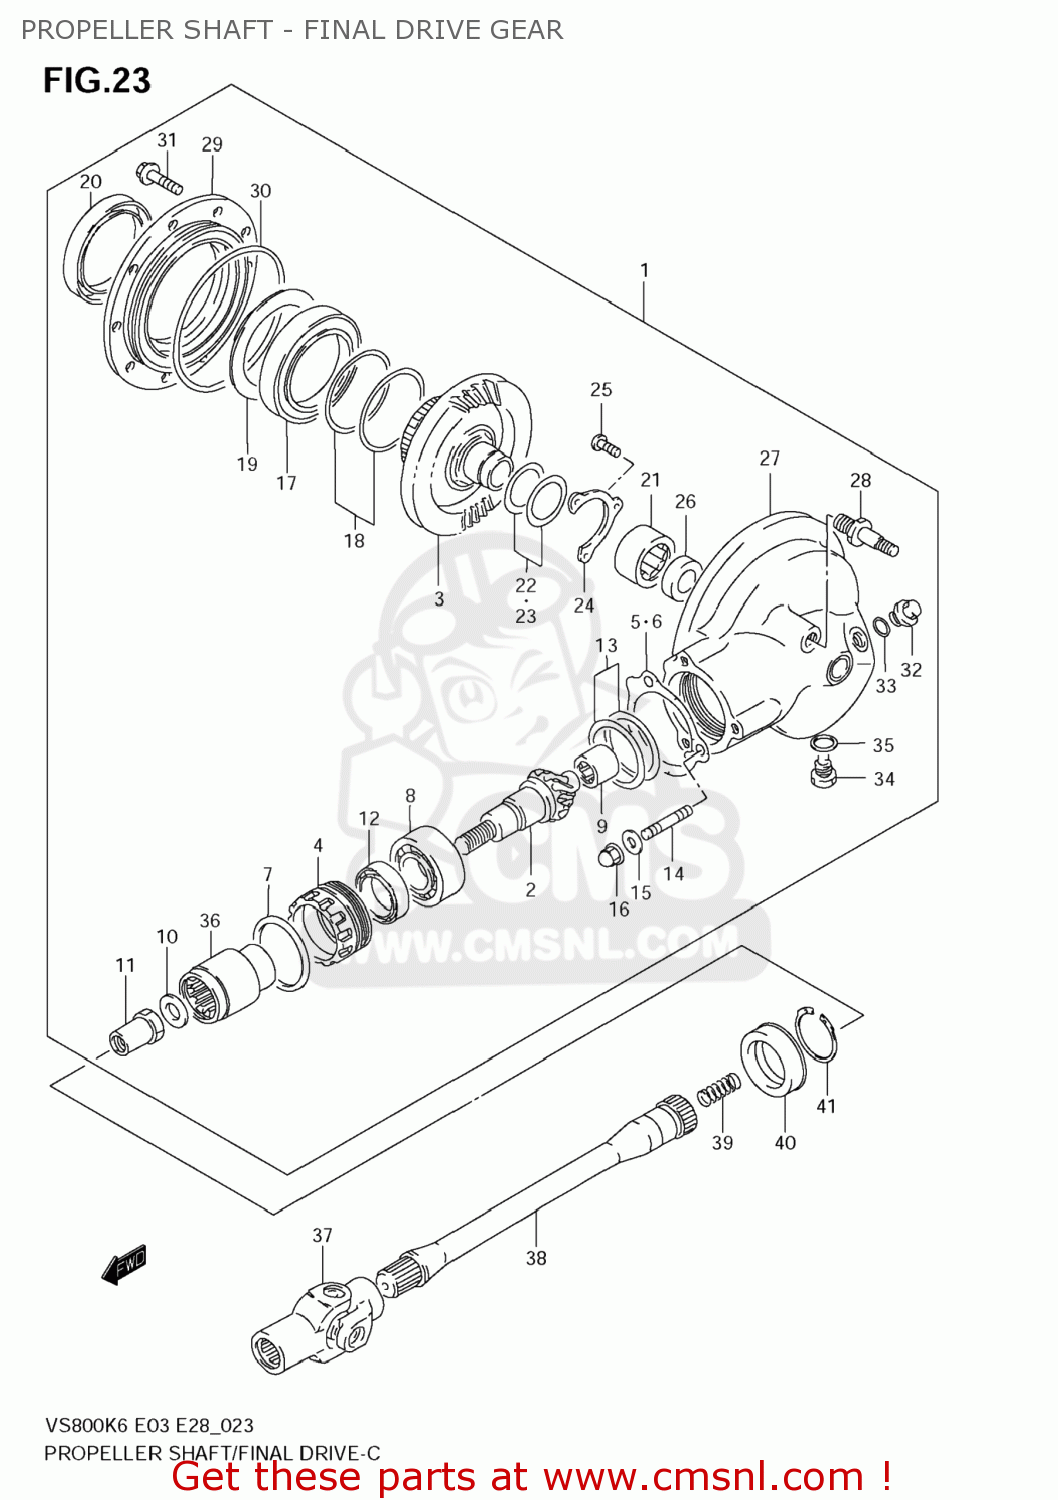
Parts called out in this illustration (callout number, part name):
1	GEAR & CASE SET,FINAL BEVEL
2	GEAR,FINAL DRIVE BEVEL(NT:11)
3	GEAR,FINAL DRIVEN BEVEL(NT:34)
4	STOPPER,FINAL DRIVE BEARING
5	PLATE,BEARING STOPPER
6	PLATE,BEARING STOPPER
7	O RING(D:1.9,ID:61.6)
8	BEARING(30X62X23.8)
9	BEARING(17X32X16)
10	WASHER(16X29X4)
11	NUT
12	SEAL,OIL(38X54X6)
13	SHIM SET,FINAL DRIVE GEAR
14	BOLT,STUD
15	WASHER
16	NUT
17	BEARING(70X110X13)
18	SHIM SET,DRIVEN GEAR BEARING
19	PLATE,FINAL DRIVEN BRG OIL
20	SEAL,OIL(70X96X16)
21	BEARING(32X46X17.7)
22	SHIM SET,FINAL DRIVEN GEAR
23	SHIM SET,FINAL DRIVE GEAR
24	RETAINER,FINAL DRIVEN GEAR BRG
25	SCREW
26	SEAL,OIL(30X42X7)
27	CASE,FINAL
28	BOLT,STUD
29	CASE,FINAL GEAR BEARING
30	O RING(D:3.5,ID:131.6)
31	BOLT
32	PLUG
33	O RING(D:2.4,ID:17.8)
34	PLUG(MAGNETO)
35	GASKET(13.8X18.8X4.8) (NAS)
36	COUPLING,FINAL DRIVE GEAR
37	YOKE COMP,UNIVERSAL JOINT
38	SHAFT,PROPELLER
39	SPRING
40	SEAL,OIL(28.4X48X15)
41	CIRCLIP
